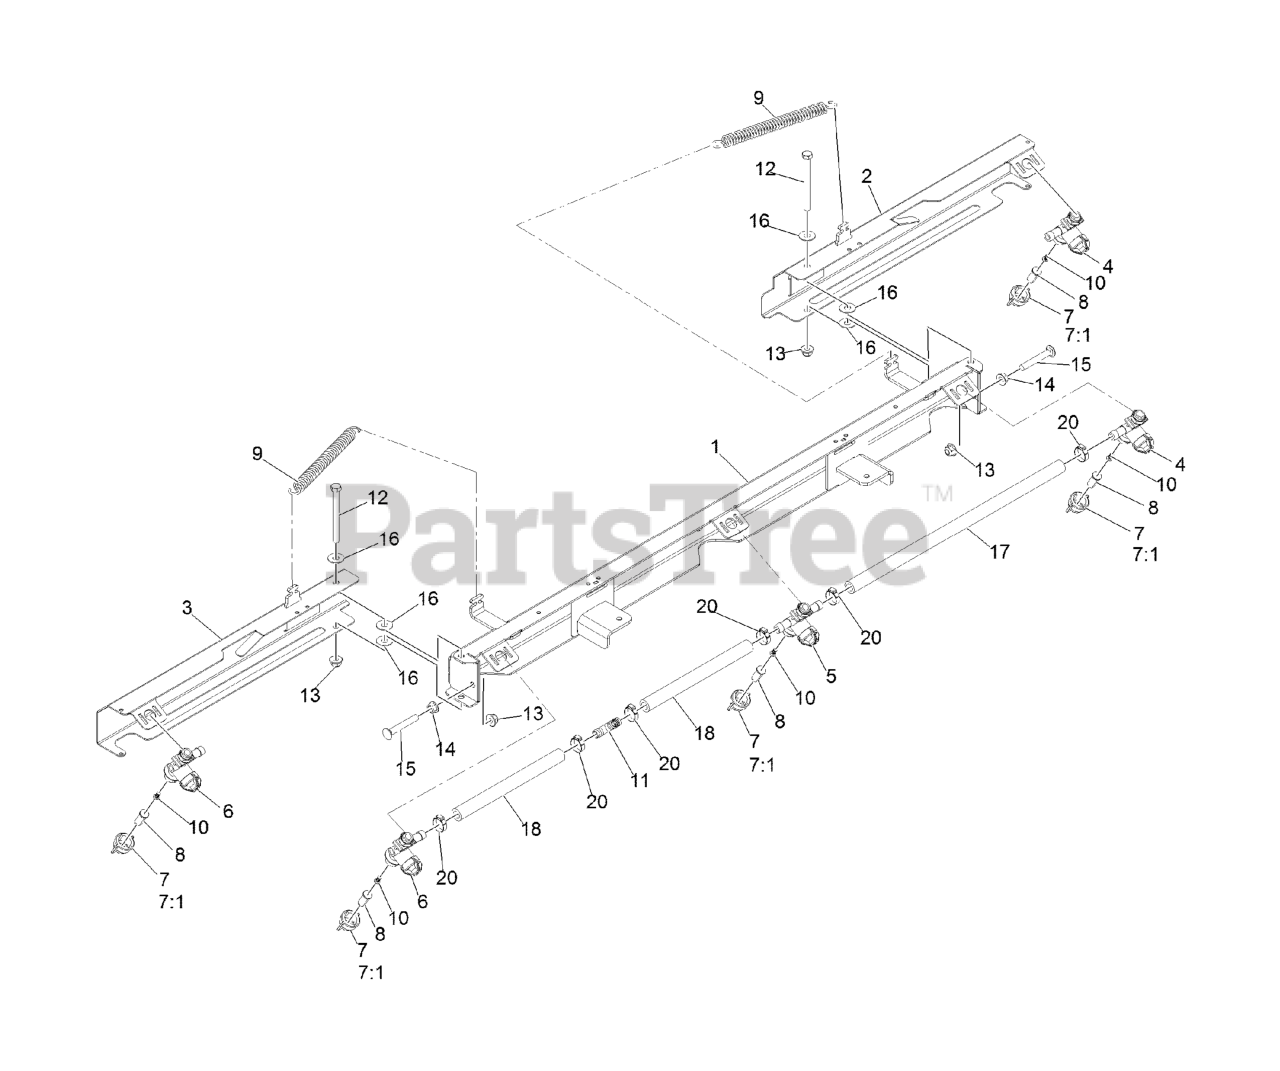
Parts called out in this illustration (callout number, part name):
1	BOOM-CENTER
2	BOOM-WING, RT
3	BOOM-WING, LT
4	BODY-NOZZLE, RIGHT
5	BODY-NOZZLE, CENTER
6	BODY-NOZZLE, LEFT
7	CAP-NOZZLE
7:1	SEAT-GASKET
8	TIP-SPRAY
9	SPRING-EXTENSION
10	STRAINER-NOZZLE, 50M 5PSI
11	FITTING-TEE, BARB
12	SCREW-HH
13	Nut-Hex Flange
14	Nut-Hex Flange
15	SCREW-CARR
16	WASHER-FLAT
17	Hose-Spray
18	Hose-Spray
20	CLAMP-OETIKER, 167
